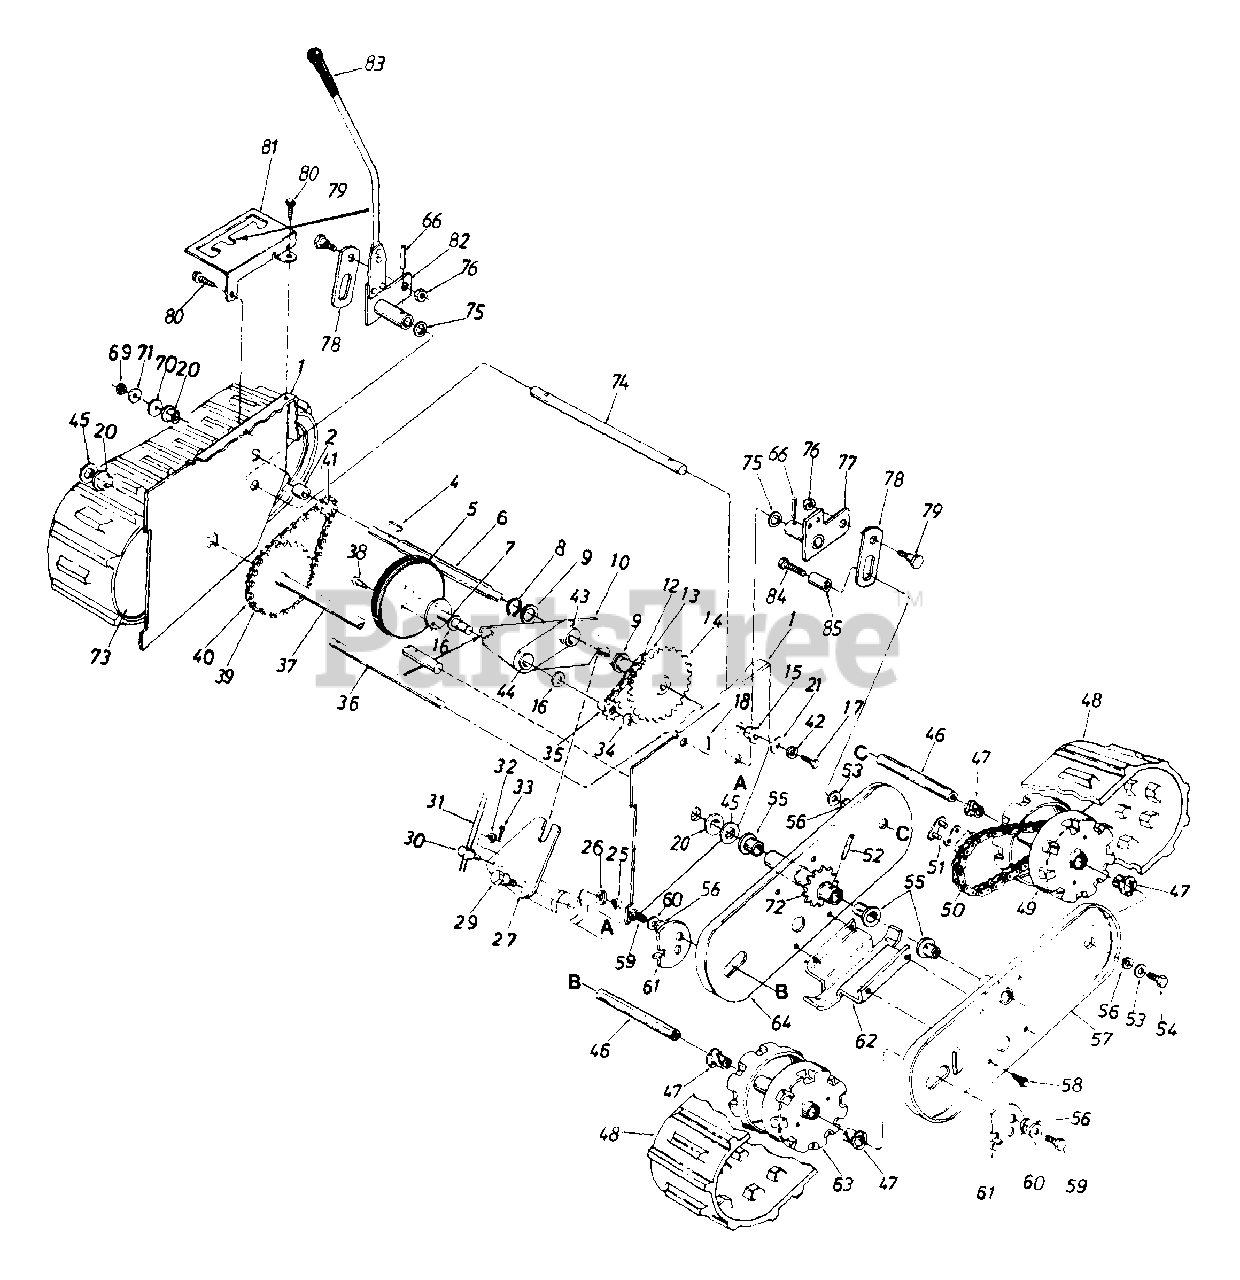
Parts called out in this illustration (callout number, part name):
1	Frame Ass'y.
2	Spacer .50" I.D. x .75" O.D. x .78" Lg.
4	#4 Hi-Pro Key 3/32 x 5/8" Dia.
5	Friction Wheel Ass'y.
6	Hex Shaft
7	Friction Wheel Mounting Plate Ass'y.
8	Snap Ring 1.00" Dia. Shaft
9	Fl-Wash. 1.00" x 1.63" O.D. x .03
10	Sliding Bracket Ass'y.
12	#41 Chain 1/2" Pitch x 35 Links
13	Master Link for #41 Chain
14	32 Teeth Sprocket Ass'y.
15	Hex Flange Brg. .630" I.D.
16	Fl-Wash. .62" I.D. x 1.00" O.D. x .06
17	Hex Lock Bolt 5/16-18 x .62" Lg
18	Cotter Pin 3/32" Dia. x .75" Lg.
20	Flange Brg. w/Flats .75" I.D.
21	Fl-Wash. .34" I.D. x 1.12" O.D. x .125
25	Hex Jam Nut 3/8-16 Thd.
26	L-Wash. 3/8" I.D.'
27	Shifting Linkage Bracket
29	Shld. Bolt .625" Dia. x .170" Lg.
30	Adjustment Ferrule
31	Shifting Rod 5/16" Dia. x 32.50" Lg.
32	Fl-Wash. .34" I.D. x .64" O.D. x .06
33	Cotter Pin 3/32" Dia. x .75" Lg.
34	Snap Ring .562" Dia. Shaft
35	Sprocket 7 Teeth x .50" Pitch
36	Shaft .50" Dia. x 9.50" Lg.
37	32 Teeth Wheel Shaft Ass'y.
38	Hex Wash. Hd. Self-Tap Scr. 5/16-24 x .50" Lg.
39	#420 Chain 1/2" Pitch x 39 Link.
40	Master Link for #420 Chain
41	8 Teeth Center Sprocket
42	L-Wash. 5/16" I.D.
43	Plastic Bearing
44	Bronze Bearing
45	Fl-Wash. .76" I.D. x 1.49 O.D.
46	Wheel Shaft 5/8 x 4.25" Lg.
47	Flange Brg. .632" I.D.
48	Snow Track 5" x 48"
49	Drive Wheel Ass'y.
50	Chain #420 x 50 Pitch x 37 Link.
51	Master Link #420
52	Spring Pin Spir. 1/4" Dia. x 1.50" Lg.
53	Bell-Wash. .345" I.D. x .88" O.D.
54	Hex Bolt 5/16-24 x .62" Lg.
55	Flange Brg. .757" I.D.
56	Fl-Wash. .510" I.D. x 1.0" O.D.
57	Outer Plate Ass'y. - L.H.
58	Hex Wash. S-Tap Scr. 1/4-20 x .50" Lg.
59	Hex Bolt 5/16-24 x .62" Lg.
60	Bell-Wash. .345" I.D. x .88" O.D.
61	Track Adjuster
66	Spring Pin 1/4" x 1.25" Lg.
69	Hex Ins. L-Nut 1/2-20 Thd.
70	Fl-Wash. .53 I.D. x 1.25 O.D. x .10
71	Bell-Wash. .50 I.D. x 1.0 O.D. x .075
72	17T Sprocket Hub Ass'y.
73	Inner Plate Ass'y. - R.H.
74	Track Lock Axle
75	Fl-Wash. 5/8 I.D. x 1" O.D.
76	Hex L-Nut 3/8-16 Thd.
77	Pivot Arm Ass'y. - L.H.
78	Slotted Link
79	Shld. Bolt .625" Dia. x .217
80	Hex Wash. AB-Tap Scr. 5/16 x .75" Lg.
81	Position Selector Plate
82	Track Lock Handle Ass'y.
84	Hex Bolt 5/16-24 x 1.25" Lg. Gr 5
85	Spacer .325" l.D.
